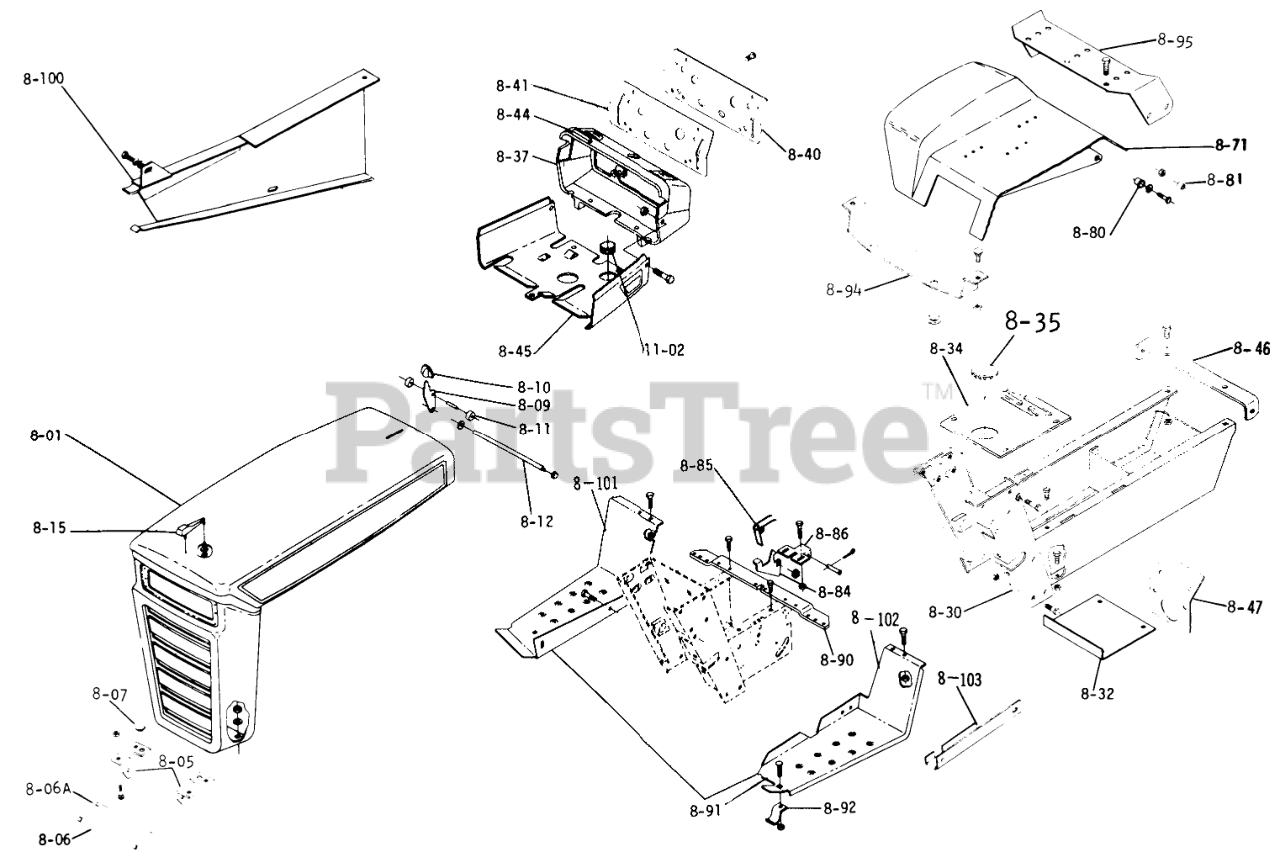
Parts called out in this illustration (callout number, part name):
8-06	GRILL PIVOT ROD
8-06A	ROD-HOOD STOP
8-07	GROMMET
8-09	LEVER HOOD LATCH
8-10	KNOB
8-15	Hood Ornament
8-32	Cover-Dust
8-35	Plug Button
8-37	Housing-Control Panel
8-71	Fender
8-80	BUSHING-FLANGED
8-85	Spring
8-92	BRACKET
